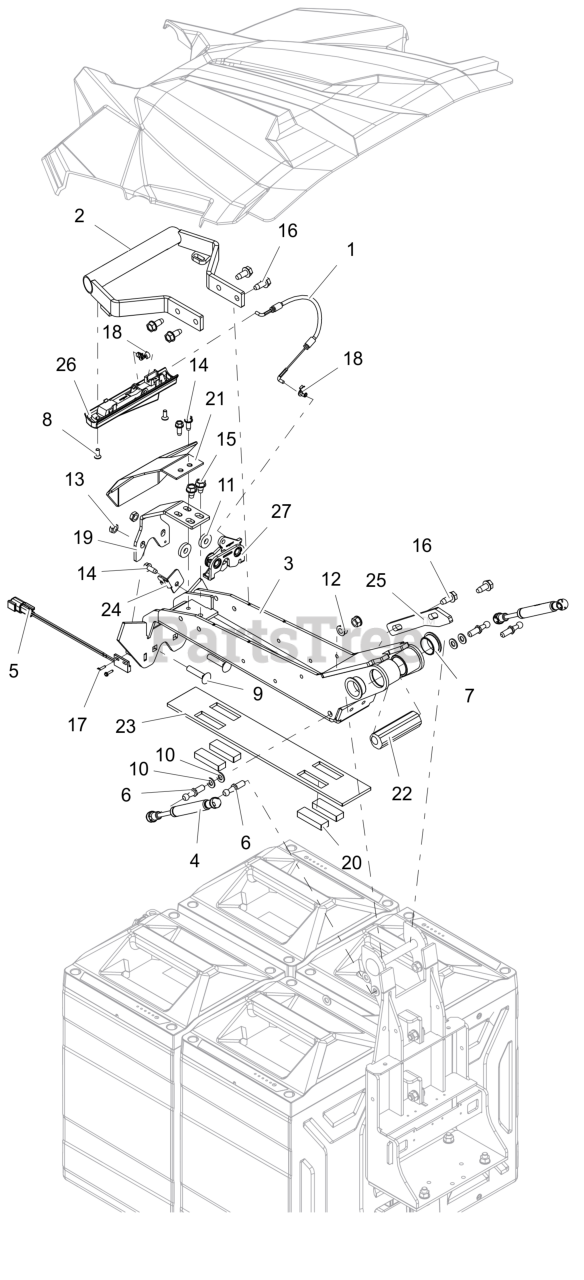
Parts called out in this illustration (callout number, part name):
1	CABLE, HOOD RELEASE
2	WLDMT, HANDLE (ORANGE)
3	WLDMT, MAIN HOLD DOWN (ORANGE)
4	DAMPER, GAS
5	SWITCH, MAGNETIC
6	STUD-BALL-THREADED
7	BSHG-FLG 1.0X1.125X.50X1.375 R
8	SCR, FLCSKH M5-0.8X14 GR10.9 ROHS
9	BLT,RHSN .31-18X1.50 G5 ZCC
10	WSHR,FLT .323X.625X.062 ZCC
11	WSHR, FLT .328X.870X.179 ZCC
12	NUT,LK-CTR-FLG .31-18 GF ZCC
13	NUT-LK-CTR-JAM .312-18 GB ZCC
14	SCR,TAP .25-20X.625 HWH ZCC
15	SCR,TAP .312-18X.50 HWH TR ZCC
16	SCR,TAP .312-18X.75 HWH TR ZCC
17	SCR-TAP #4-40x.50 HWH ZCC
18	CLIP, RETAINER
19	BRKT, LATCH MTG (ORANGE)
20	PAD, RUBBER
21	COVER, LATCH (ORANGE)
22	ECCENTRIC, HOOD LATCH-FRONT
23	PAD, RUBBER
24	RETAINER, CABLE (BLACK)
25	STOP, HOOD (BLACK)
26	HANDLE, SQUEEZE ACTUATOR
27	LATCH, PUSH TO CLOSE
